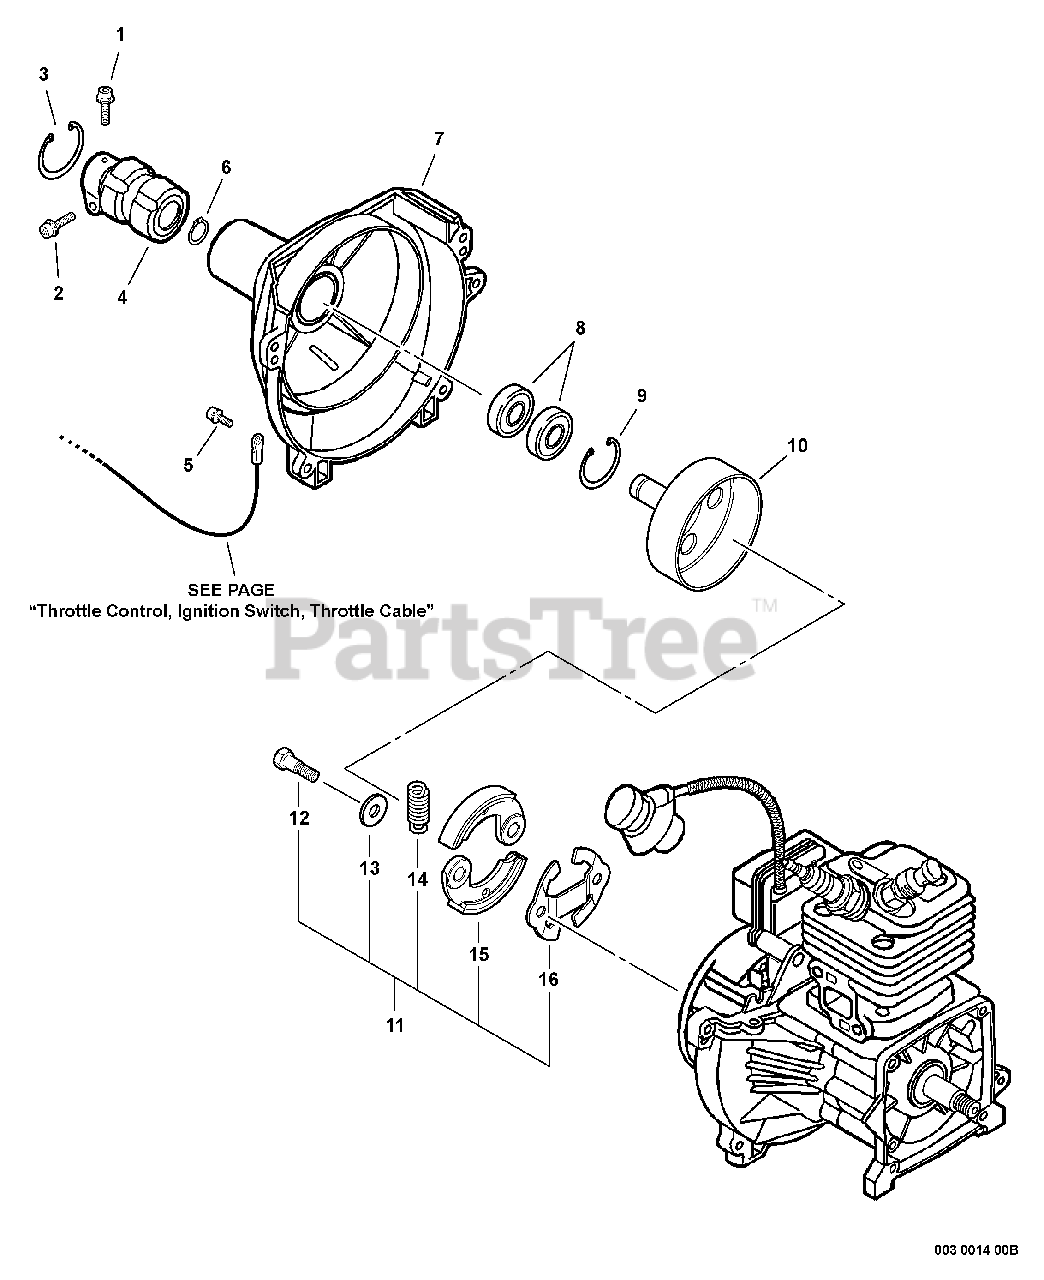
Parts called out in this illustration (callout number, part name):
1	BOLT 5×12
2	BOLT 5×28
3	RING, RETAINING Ø45
4	CUSHION
5	BOLT 5×20
6	RING, RETAINING - 12
7	COVER, FAN
8	BEARING, BALL 6001
9	RING, SNAP 28
10	DRUM, CLUTCH
11	CLUTCH ASSY
12	BOLT, CLUTCH
13	WASHER 10.2×18×1.0
14	SPRING, TENSION
15	SHOE, CLUTCH
16	WASHER, FLAT
